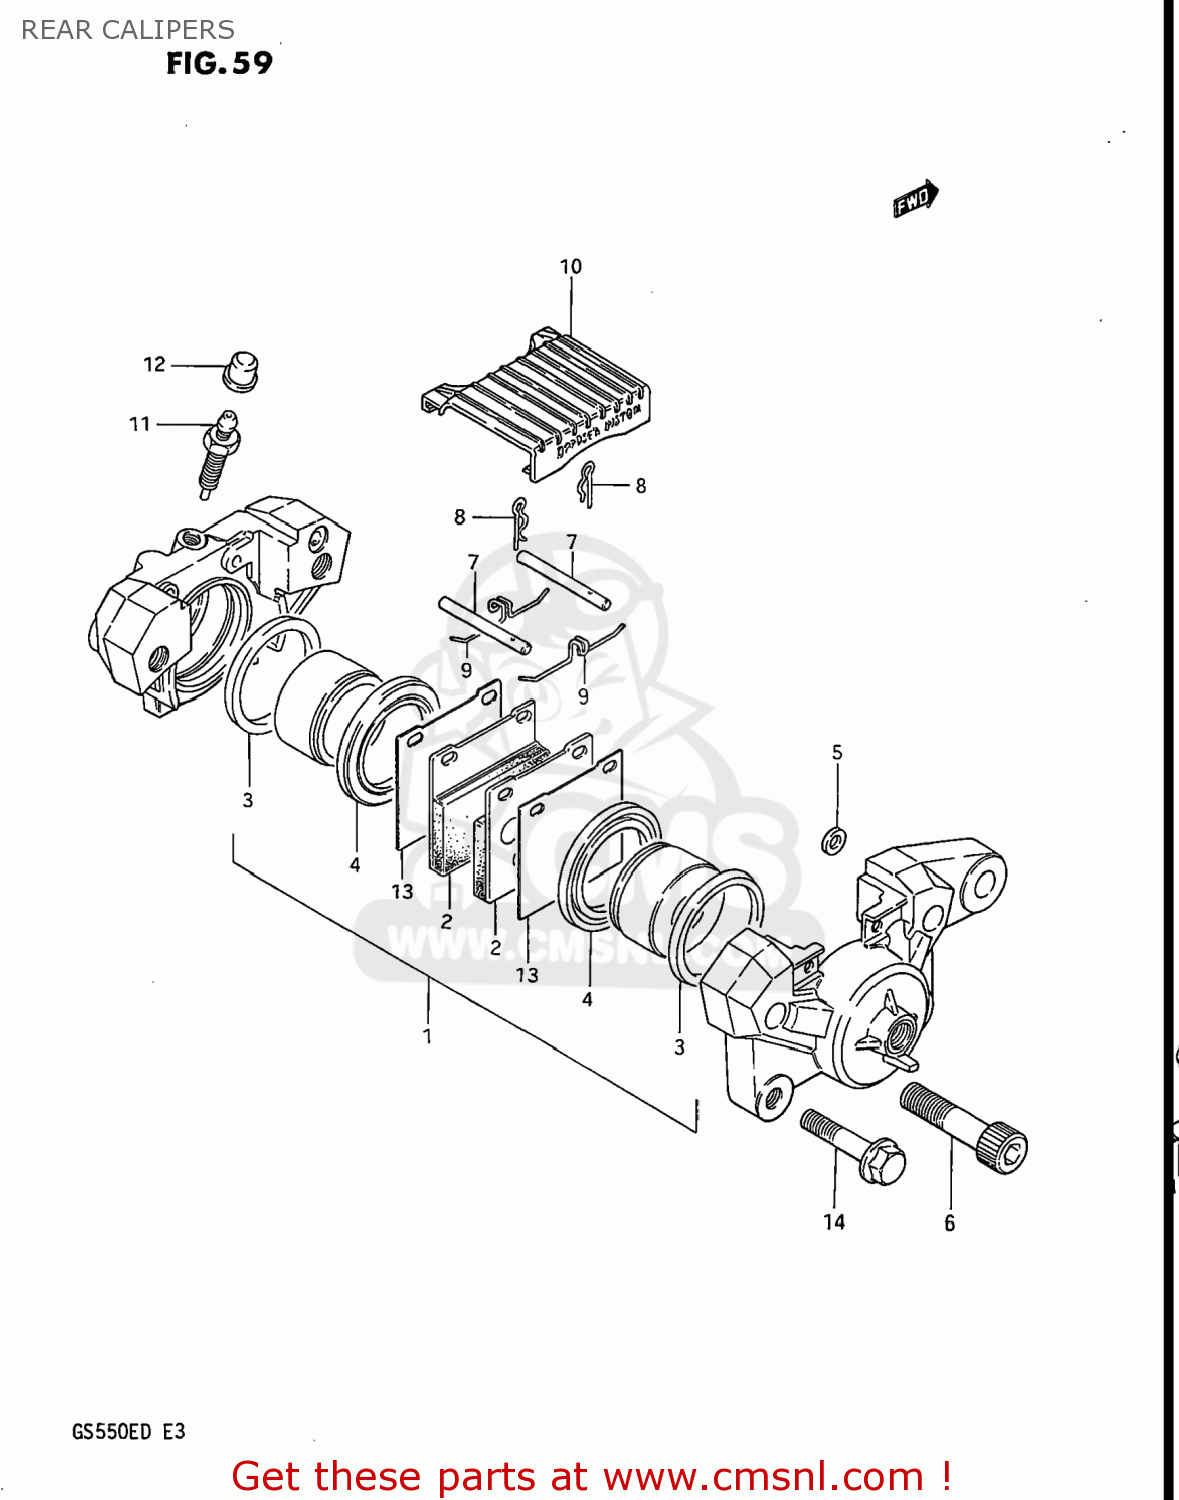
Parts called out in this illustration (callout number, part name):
1	PISTON SET
2	59130-16700 (MCA)
3	SEAL,PISTON
4	BOOT
5	SEAL,JOINT
6	BOLT,CALIPER HOUSING
7	PIN,PAD
8	CLIP,PAD PIN
9	SPRING
10	COVER,CALIPER
11	BLEEDER
12	CAP,BREATHER
13	SHIM,PAD
14	BOLT
